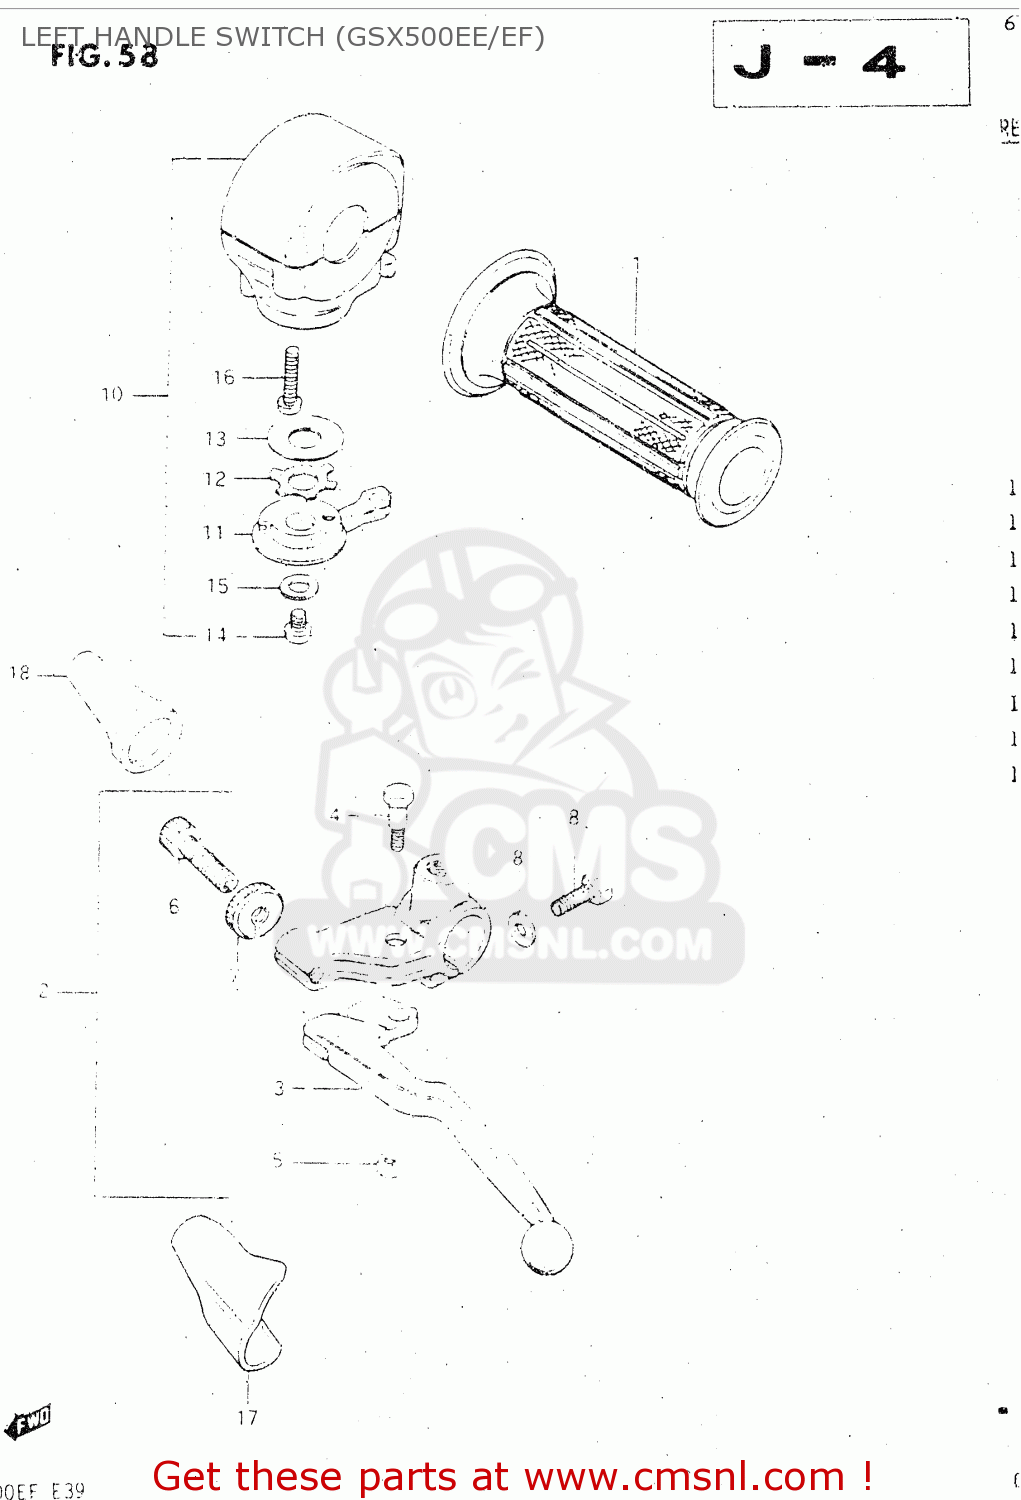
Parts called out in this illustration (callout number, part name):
1	GRIP,L
2	LEVER ASSEMBLY,CLUTCH
3	LEVER,CLUTCH
4	BOLT,LEVER PIVOT
5	NUT
6	ADJUSTER,CABLE
7	NUT,CABLE ADJUSTER LOCK
8	BOLT
9	WASHER
10	SWITCH ASSY, HANDLE LH
11	LEVER,STARTER
12	WASHER
13	WASHER
14	SCREW
15	WASHER 6MM
16	SCREW
17	COVER,CLUTCH LEVER
18	BOOT,CLUTCH CABLE
